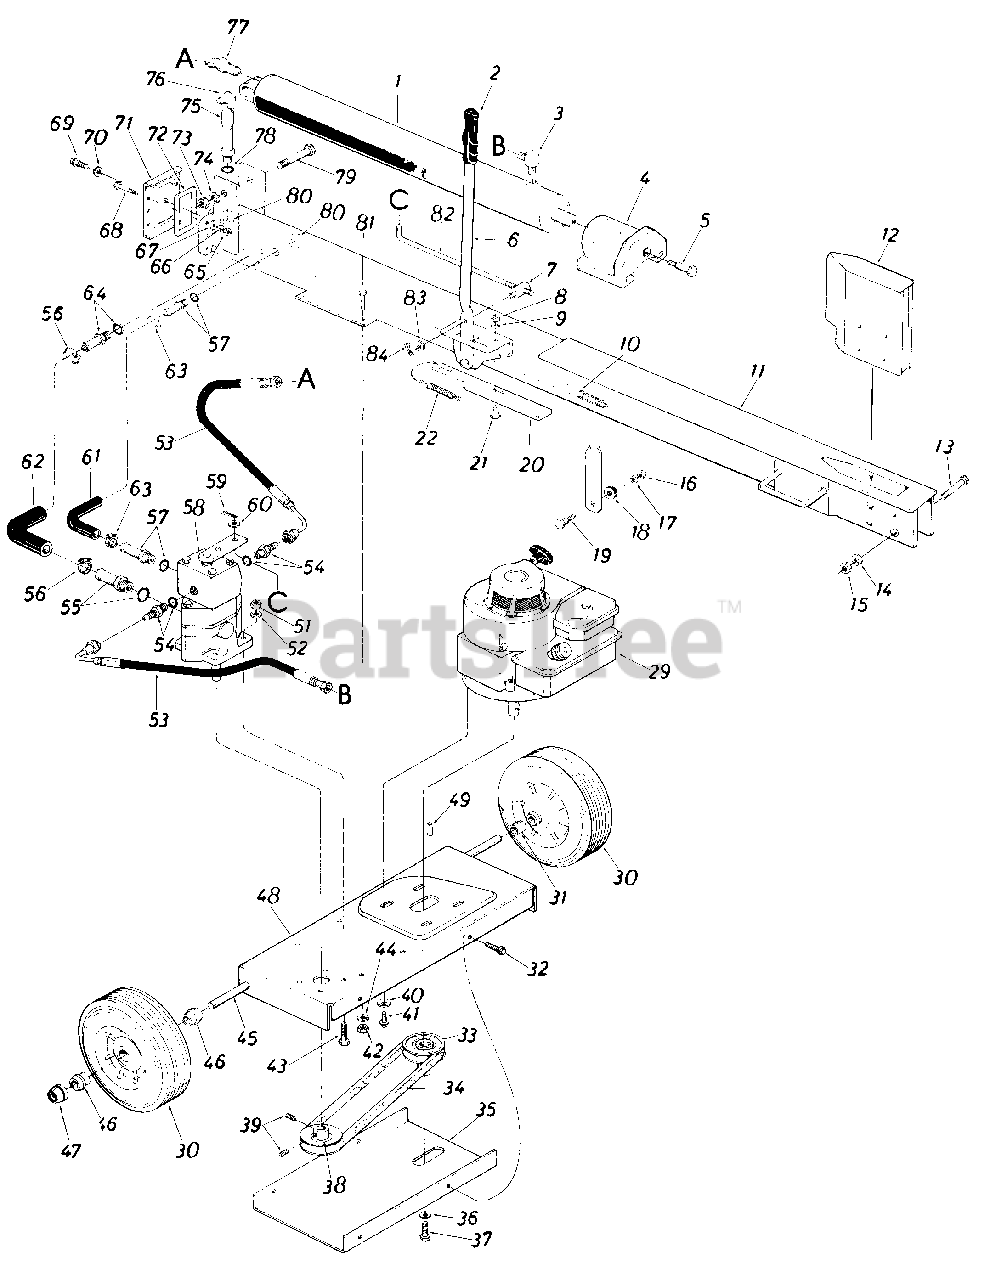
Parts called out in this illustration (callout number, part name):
1	2-1/2" Cylinder Ass'y. Comp.
2	Grip
3	90ø Elbow Adapter
4	Pusher Plate
5	Shoulder Bolt 5/8" Dia. x .660" Lg. 1/2-13 Thd.
6	Engagement Handle
7	Adjustment Ferrule
8	Hex Nut 5/16-18 Thd.*
9	L.-Wash. 5/16" I.D.*
10	Strainer Tube Ass'y.
11	Oil Tank Ass'y. Comp
12	Wedge Ass'y.
13	Hex Bolt 5/8-18 x 3.50" Lg. (Grade 5)
14	L.-Wash. 5/8" I.D.
15	Hex Nut 5/8-18 Thd.*
16	Hex Nut 3/8-16 Thd.*
17	L.-Wash. 3/8" I.D.*
18	Rubber Wash.
19	Shoulder Bolt .498x .340
20	Engagement Brkt.
21	Shoulder Bolt .437" Dia. x.180" Lg.
22	Extension Spring .50" O.D. x 4. 25" Lg.
29	Engine-B&S
30	Wheel Ass'y. Comp. 10.0" x 2.75
31	Sleeve .632" I.D. x .875" O.D. x.90" Lg.
32	Hex Wash. Hd. Self Tap. Scr. 1/4-20 x .50" Lg.
33	1/2" V-Pulley 7/8" I.D. x 7/8" I.D. x 3-1/4" O.D.
34	"V"-Belt (4L) 1/2" V x 30" Lg.
35	Belt Cover
36	L.-Wash. 5/16" I.D.*
37	Hex Bolt 3/8-24 x 1.0" Lg.*
38	1/2 (4L) "V"-Pulley 5/8" I.D. x 3-1/2" O.D.
39	Set Scr. 1/4-28 x .25" Lg.
40	Bell.-Wash..40" I.D. x .88"O.D.
41	Hex Wash. Hd. TT-Tap Scr. 3/8-16 x .87" Lg.
42	Hex Nut 5/16-24 Thd.*
43	Hex Bolt 5/16-18 x 1.00" Lg.*
44	L.-Wash. 5/16" I.D." I
45	Axle Shaft 5/8 Dia. x 25.5" Lg.
46	FlangeBrg.w/Flats.631" I.D.
47	Push Cap 5/8" Dia. Rod
48	Frame-Engine
49	Sq. Key 3/16" x 3/16" x 1.50" Lg.*
51	Hex Nut 5/16-18 Thd.*
52	L.-\l\lash. 5/16" I.D.*
53	High Pressure Hose
54	Adapter-or Boss to MJIC 9/16-18 to 7/16-20
55	Adapter 3/4" Tubing to 3/4-16 M-Boss
56	Hose Clamp 5/8" I.D.
57	Adapter 1/2" Tube 9/16-18 or M-Boss
58	Valve Ass'y.
59	Cotter Pin 3/32" Dia. x .75" Lg. *
60	Fl.-Wash. 344" I.D. x .62" O.D. x .063
61	Return Hose.50" I.D.
62	Suction Hose.75" I.D.
63	Hose Clamp 1/4" I.D.
64	Adapter 1.0" Tube 1-1/16-12 "O"-Ring
65	Hex Nut 5/16-18 Thd.*
66	L.-Wash. 5/16" I.D.*
67	Fl.-Wash. .343" I.D. x .687" O.D. x .062
68	Hex Bolt 5/16-18 x 1.50"
69	Hex Hd. Tap Scr. 5/16"
70	Gasket
71	End Plate
72	Gasket
73	H ex u t 3/4" Thd . *
74	L.-Wash. 3/4" I.D.*
75	Filler Tube Ass'y.
76	Oil Fill Cap
77	45ø Male Adapter 7/16-20 MJ-1/4-18 NP
78	"O"-Ring.92" I.D. x 1.16" O.D. x .116 Dia.
79	Hex Bolt 3/4" x 4.0" Lg.
80	Hex Nut 11/16-1 Thd.
81	Hex Bolt 5/1 6-24 x 1 .00" Lg. (Grade 5)
82	Engagement Rod 16.75" Lg.
83	Fl.-Wash. .344" I.D. x.62" O.D. x .063
84	H air Pin Cotter 5/1 6" Dia.
